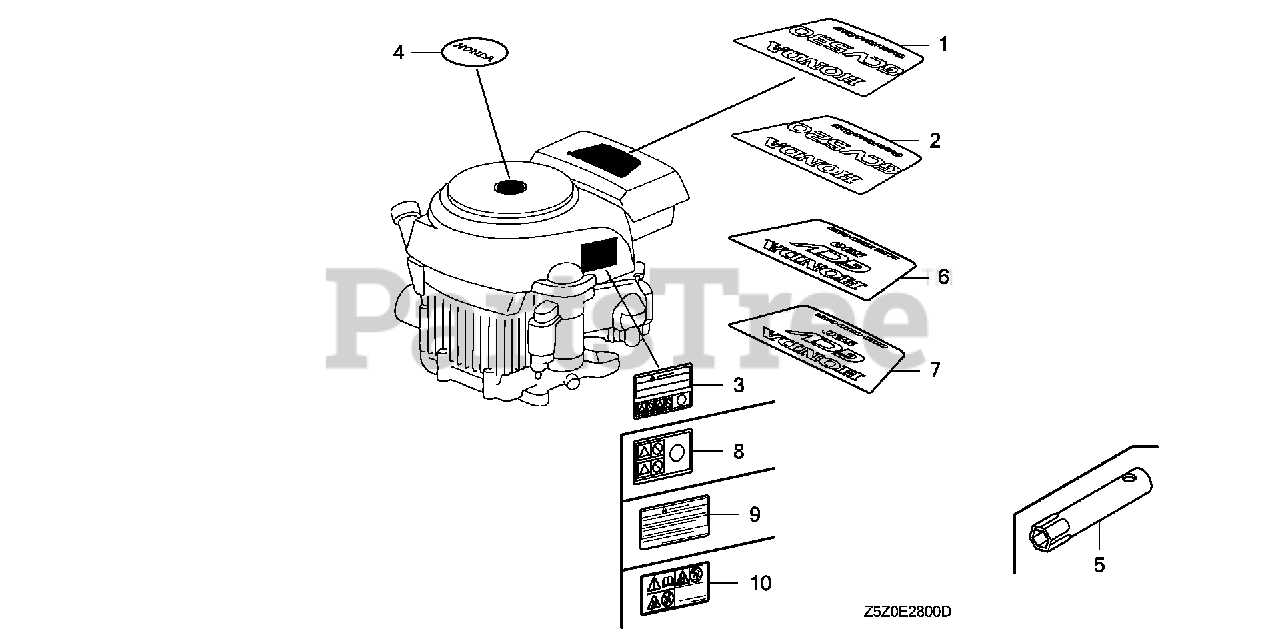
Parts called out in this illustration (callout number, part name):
2	MARK, EMBLEM (GCV520)
3	MARK, OPERATOR CAUTION (ENGLISH)(MADE IN JAPAN)
3	MARK, OPERATOR CAUTION (FRENCH)(MADE IN JAPAN)
4	MARK, HONDA
7	MARK, EMBLEM (GCV520)
8	MARK, OPERATOR CAUTION (PICTOGRAPH)(MADE IN JAPAN)
